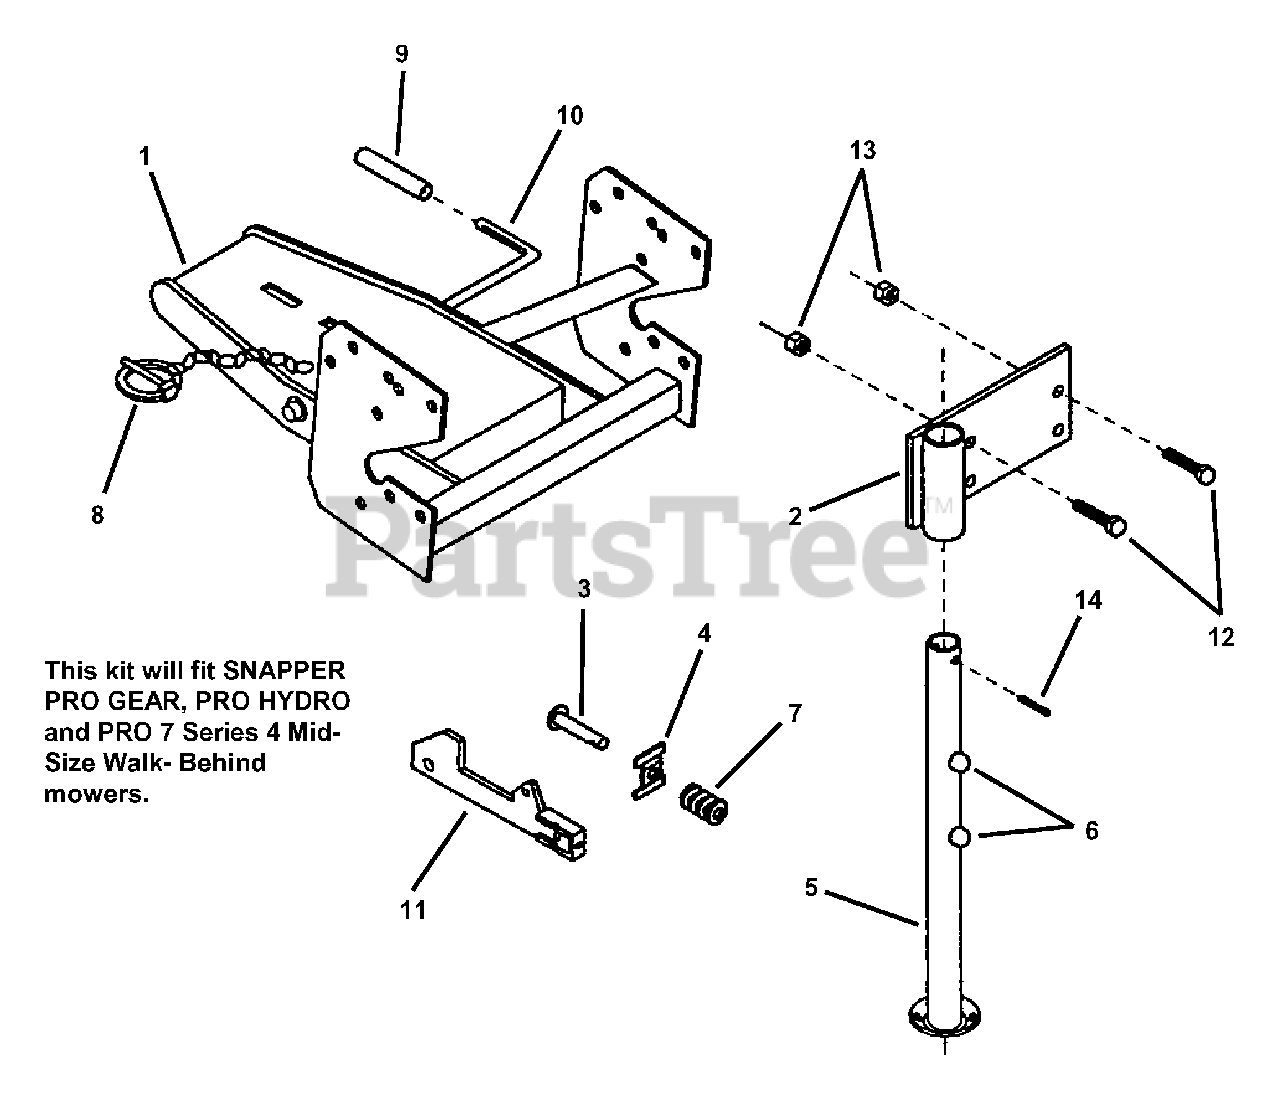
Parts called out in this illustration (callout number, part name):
1	HITCH, Male Quick
2	SUPPORT, Parking Stand
3	PIN, 1/4" x 1-11/16" Clevis
4	PLATE, Spring
5	STAND, Parking
6	BUTTON, Snap
8	ASSEMBLY, Chain & Linch Pin
9	GRIP, Handle
10	LEVER, Male Hitch
12	BOLT, 3/8-16 x 1" Hex Head, Grade 5
13	NUT, 3/8-16 Hex Lock
14	PIN, 5/32 x 2" Cotter
